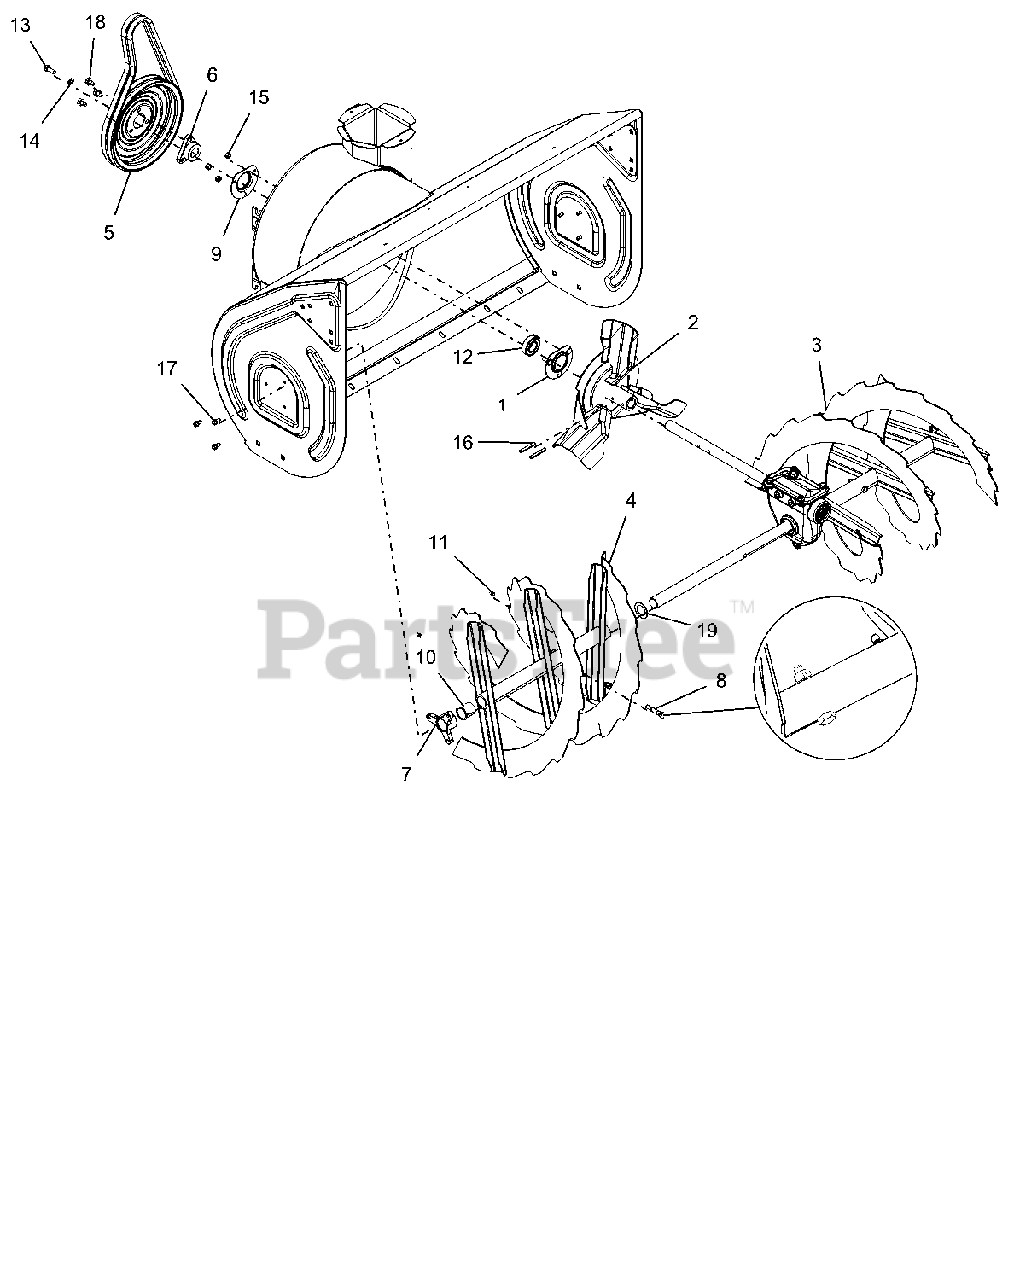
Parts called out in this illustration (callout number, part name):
1	BEARING FLANGE
2	IMPELLER, 3 BLADE-14"
3	RAKE, LH-36" (1 ID X 15.75 OD)
4	RAKE, RH-36"(1 ID X 15.75 OD)
5	PULLEY, SPIN FORM DUAL GROOVE
6	PULLEY HUB, D-BORE .87 PRO
7	BUSHING, RAKE SHAFT 1"
8	SHEAR BOLT SERVICE ASSEMBLY
9	BEARING FLANGE
10	BSHG-FLG SPLIT NYLINER 1.0" HP
11	ZERK,FITTING .25X.125 DRIVE IN
12	BRG-BALL .876X1.75X.50 RSTFP
13	BLT-HEX .31-24X.75 YWZC GR5
14	WSHR-LK .312X.097 HVY YWZC
15	@NUT-LK-CTR .25-20 YWZC
16	PIN-ROLL .250X1.75
17	SCR-TAP .25-20X.50 HWH TR YWZ
18	@SCR-TAP .31-18X.50 HWH TR YWZ
19	WSHR-FL-STL 1.010X1.505X.062YZ
